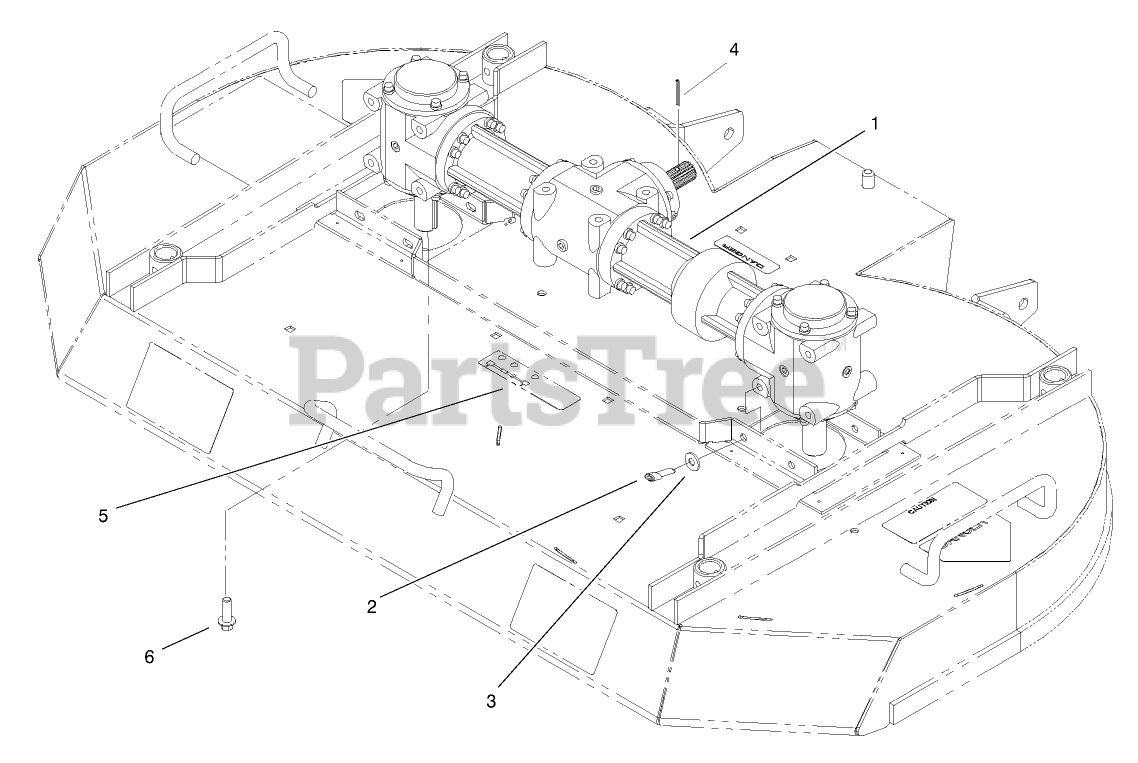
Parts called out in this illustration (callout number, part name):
1	Gearbox ASM
2	SCREW-HSH
3	WASHER
4	PIN-SPRING
5	Decal-Gearbox Lube, Ofz
6	BOLT-BLADE, LH THREAD
